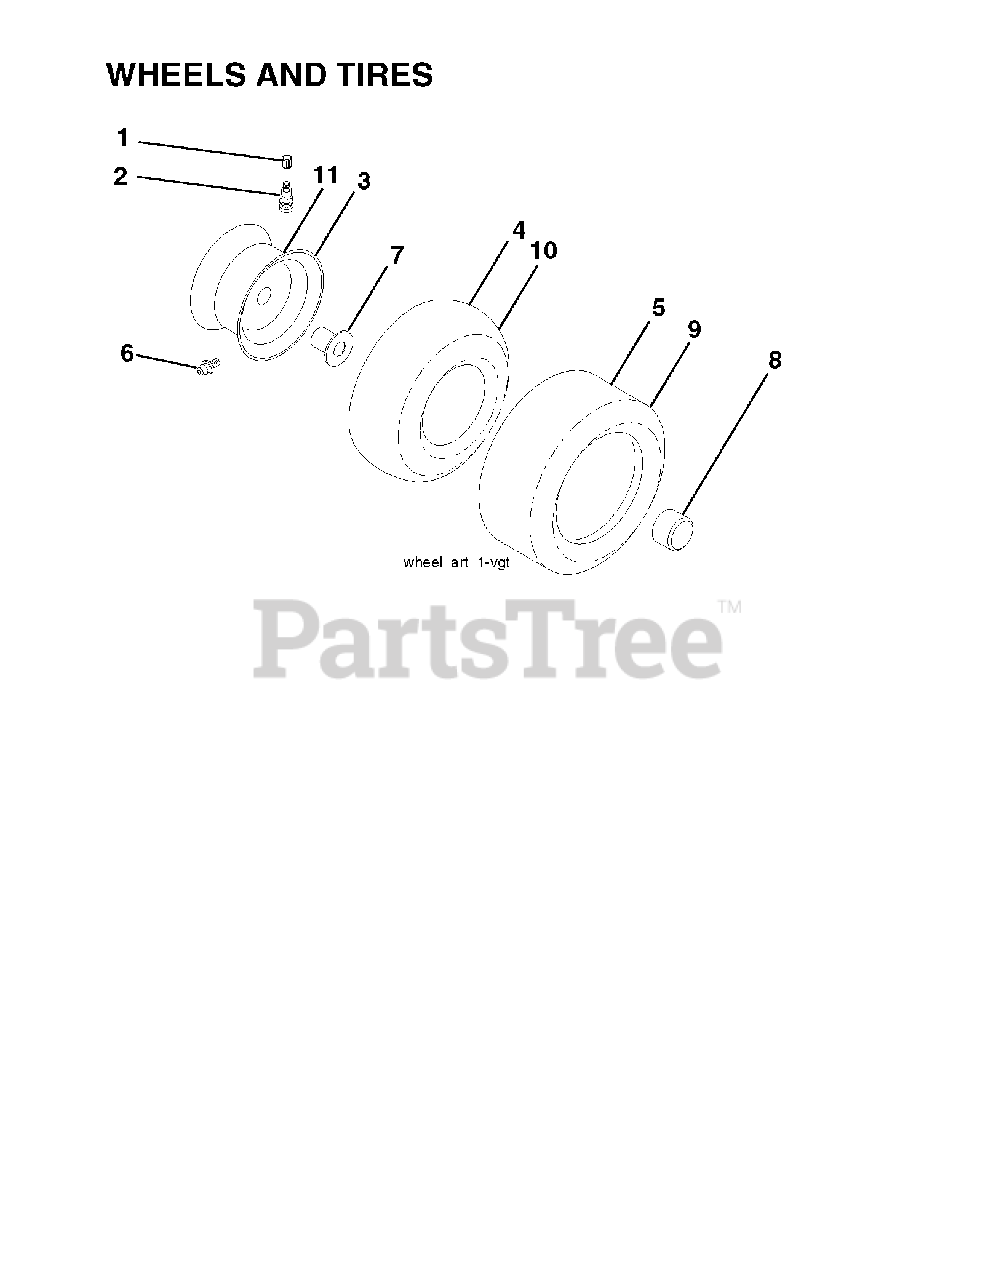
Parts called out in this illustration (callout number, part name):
1	VALVE CAP
2	VALVE STEM LT
4	TUBE.5.3/4.5/6
6	FITTING LT
7	Flange Bearing
9	TIRE 20X8-8 TURF SAVER
11	RIM 8" SILVER
